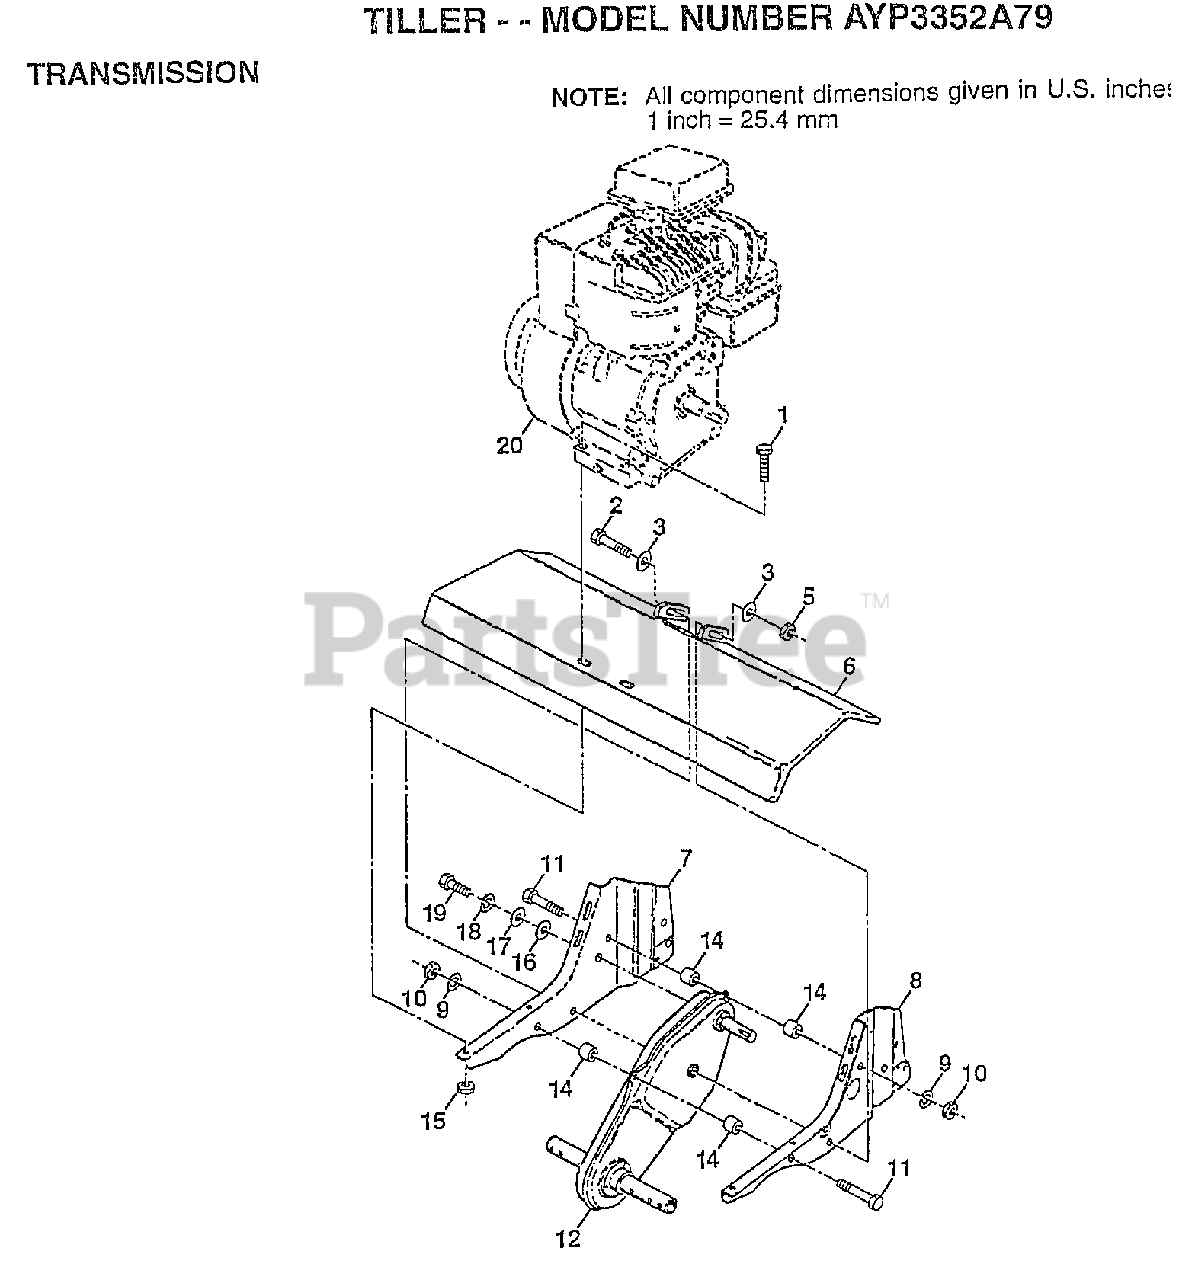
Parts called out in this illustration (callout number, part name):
1	BOLT.HEX.5/16-1.5
2	BOLT HEX 3/8-16
3	WASHER
5	NUT
6	"SHIELD, TINE"
7	BRACKET, ENGINE RH
8	BRACKET, ENGINE LH
9	LOCKWASHER
10	NUT.HEX.5/16-18
14	SPLIT SPACER RT
16	WASHER
17	WASHER
18	LOCKWASHER
19	BOLT
